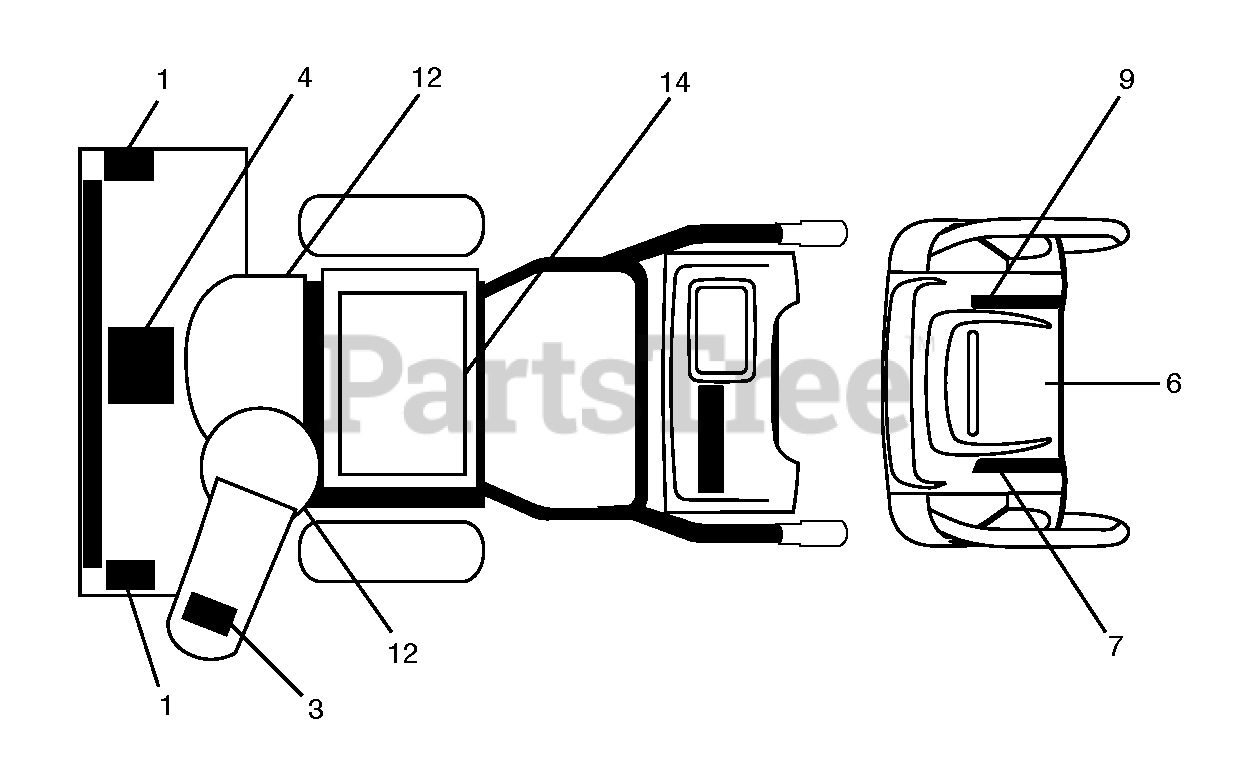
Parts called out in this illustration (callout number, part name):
1	DECAL.AUGER.SAFETY.
3	DECAL.CHUTE.SAFETY.
4	DECAL.AUGER."
6	DECAL.CONSOLE.INSTRUCTION
7	DECAL.CONS.LT.WO/DEFL
9	DECAL.CONS.RT.SPD/LEV/PWRST
12	DECAL.BELT.GUARD.
14	DECAL.FENDER
